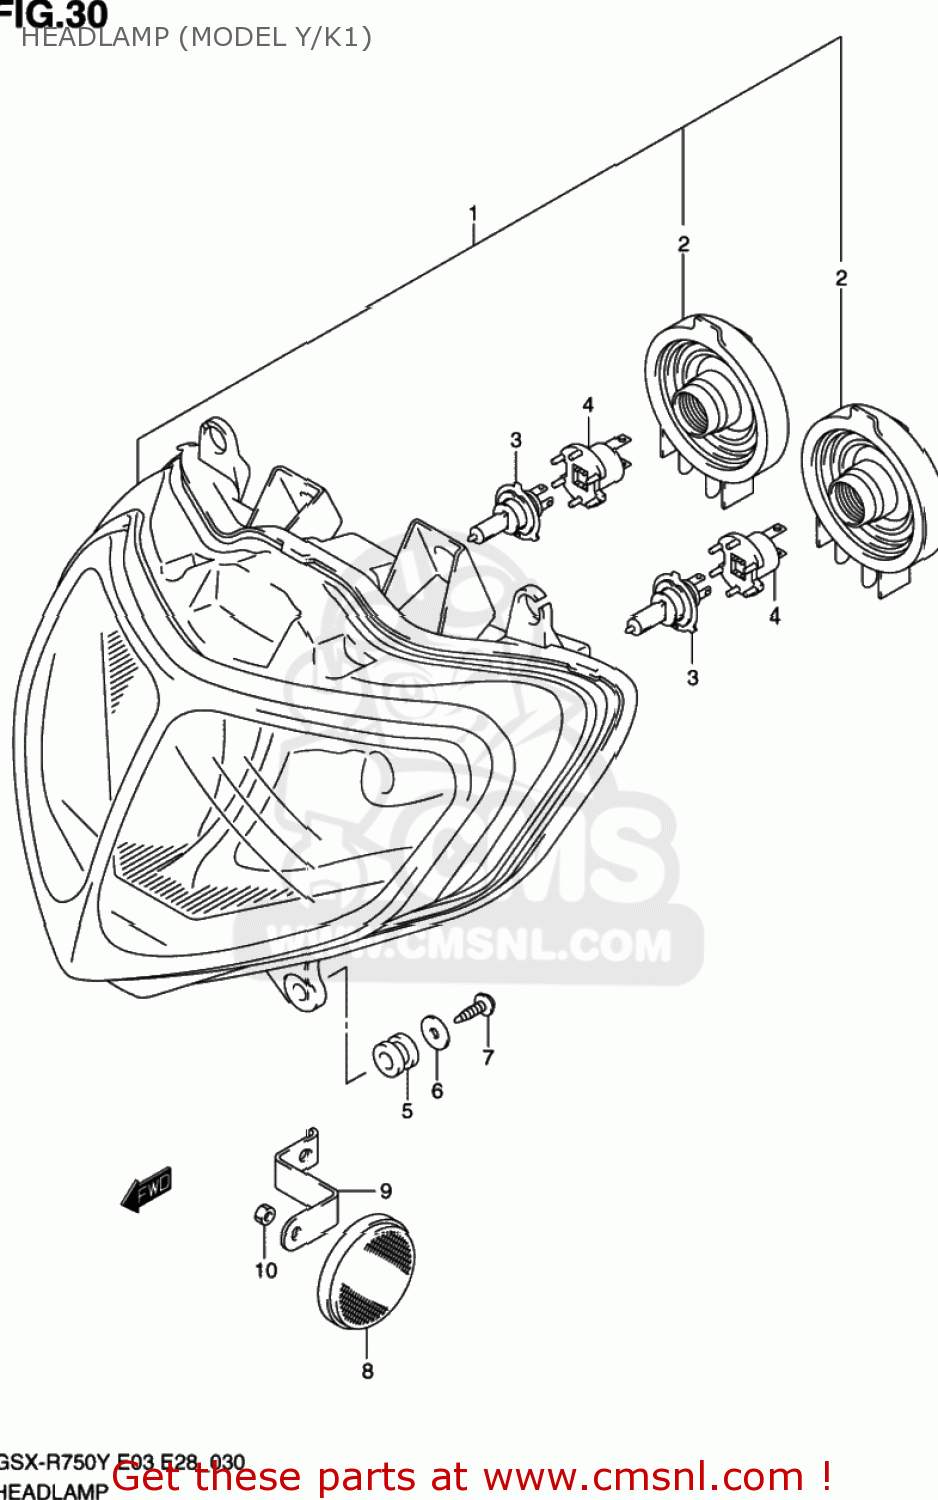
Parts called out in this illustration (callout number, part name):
1	HEADLAMP ASSY
2	COVER,SOCKET
3	BULB(12V55W/H7/PX26D/PHILIPS)
4	ADAPTER ASSY
5	CUSHION
6	WASHER(5.5X18X1)
7	SCREW(5X16)
8	REFLECTOR,REFLEX FR
9	BRACKET,FR SIDE RR
10	NUT
